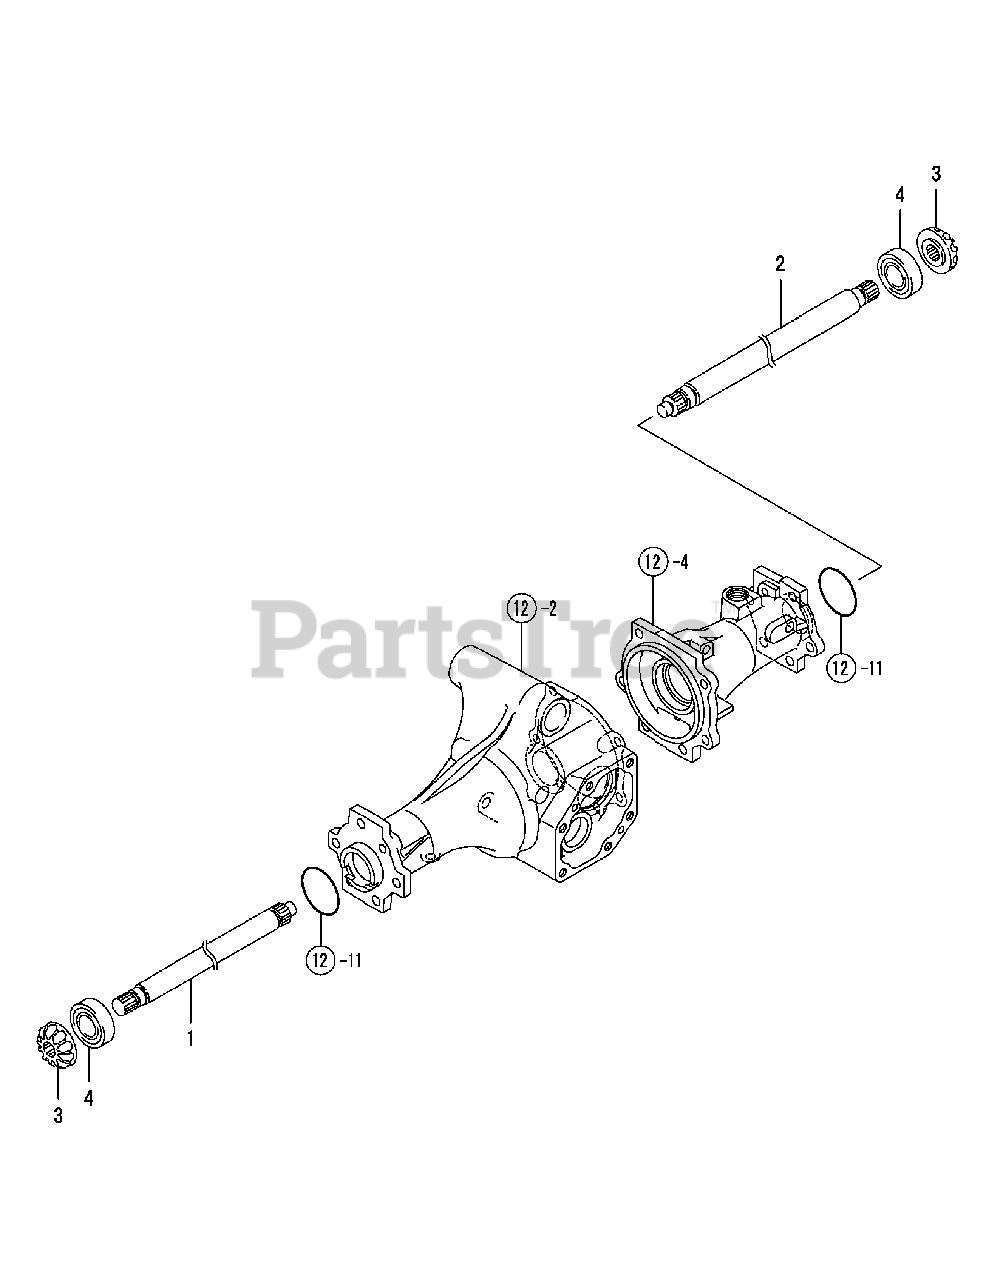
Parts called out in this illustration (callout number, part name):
1	Shaft L,Front 1
2	Shaft R,Front 1
3	Gear, 1-2 Shaft
